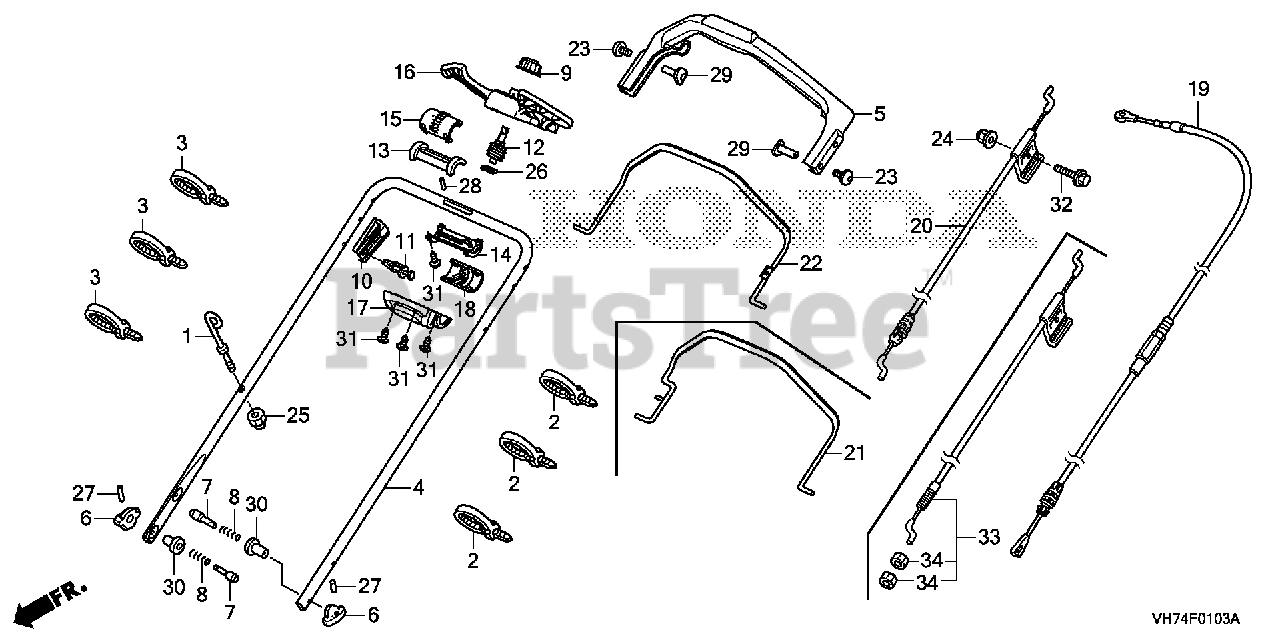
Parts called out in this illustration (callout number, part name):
1	GUIDE, ROPE
2	TIE, CABLE (157.5MM)
3	TIE, CABLE (157.5MM)
4	PIPE, HANDLE *NH105* (MAT BLACK)
5	COVER, HANDLE (UPPER)
6	GRIP, HANDLE JOINT *NH164* (GRIP GRAY)
7	PIN (8MM)
8	SPRING, HANDLE ADJUSTING
9	SELECTOR, CHANGE
12	GEAR, CLUTCH ADJUST
13	BRACKET, GRIP (UPPER)
14	BRACKET, GRIP (LOWER)
15	COVER, BRACKET (UPPER)
16	GRIP, CLUTCH (UPPER)
17	GRIP, CLUTCH (LOWER)
18	COVER, BRACKET (LOWER)
19	CABLE, CLUTCH
21	LEVER, ROTO-STOP *NH105* (MAT BLACK)
23	BOLT, HANDLE HOLDER
25	NUT, NYLON LOCK (6MM)
26	SPRING, CLUTCH GEAR
27	PIN, COILED (2X12)
28	ROLLER (5X37.3)
29	COLLAR, HANDLE HOLD
30	COLLAR, HANDLE HEIGHT ADJUSTING
31	SCREW, TAPPING (4X12)
